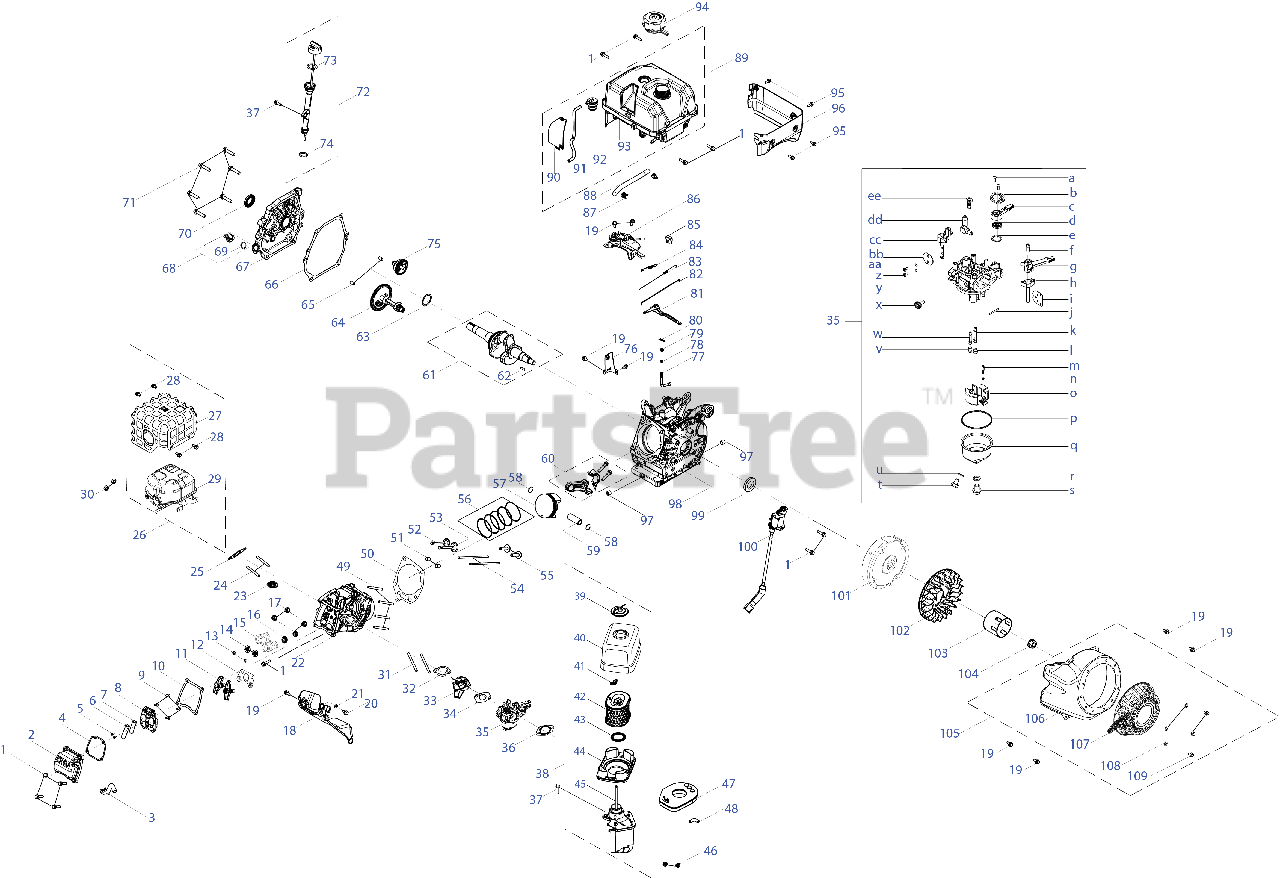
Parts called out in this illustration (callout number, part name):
1	BOLT M6-1 x 25 GR8.8
2	VALVE COVER
3	BREATHER HOSE
4	VALVE COVER GASKET
5	SCREW M3x8
6	BREATHER PLATE
7	BREATHER VALVE
8	INNER VALVE COVER
9	SCREW M5x12
10	VALVE COVER GASKET
11	ROCKER ARM
12	ROCKER ARM BASE
13	VALVE CLIP
14	VALVE SPRING SEAT
15	VALVE SPRING
16	INTAKE VALVE SEAL
17	NUT M8
18	ENGINE SHROUD
19	BOLT M6-1 x 12 GR8.8
20	BOLT M6-1 x 14 GR8.8
21	FLAT WASHER 6x1x18
22	CYLINDER HEAD
23	SPARK PLUG
25	MUFFLER GASKET
26	MUFFLER
27	MUFFLER GUARD
28	BOLT M6x10
29	MUFFLER
31	STUD M6x123
32	INSULATOR GASKET
33	CARBURETOR GASKET
34	CARBURETOR GASKET
35	CARBURETOR
36	INSULATOR
37	BOLT M6-1 x 18 GR8.8
38	AIR FILTER ASSEMBLY
39	PLASTIC WING NUT
40	AIR FILTER COVER
41	WING NUT
42	AIR FILTER ELEMENT
43	AIR FILTER GASKET
44	AIR FILTER BASE (UPPER)
45	AIR FILTER BASE (LOWER)
46	HEX NUT
47	CARBON CANISTER
48	CARBON CANISTER HOSE
49	STUD M8x60
50	CYLINDER HEAD GASKET
51	DOWEL PIN
52	EXHAUST VALVE
53	INTAKE VALVE
54	PUSH ROD
55	TAPPET
56	PISTON RING SET
57	PISTON
58	PISTON PIN SNAP RING
59	PISTON PIN
60	CONNECTING ROD
61	CRANKSHAFT
62	FLYWHEEL KEY
63	THRUST WASHER
64	CAMSHAFT
65	DOWEL PIN
66	CRANKCASE GASKET
67	CRANKCASE COVER
68	OIL PLUG
69	O-RING 15.8 x 2.5
70	OIL SEAL 25 x 41.25 x 6
71	BOLT M8x35
72	DIPSTICK
73	O-RING
74	O-RING
75	GOVERNOR GEAR
76	DIPSTICK BRACKET
77	GOVERNOR GEAR SHFT
78	O-RING
79	GOVERNOR SEAL
80	COTTER PIN
81	GOVERNOR LEVER
82	THROTTLE LINKAGE
83	IDLER SPRING
84	GOVERNOR SPRING
85	THROTTLE KNOB
86	GOVERNOR GEAR BRKT ASM
87	HOSE CLAMP
88	FUEL HOSE
89	Fuel Tank
90	VENT HOSE COVER
91	FUEL HOSE
92	ROLLOVER VALVE
93	FUEL TANK
94	FUEL CAP
95	BOLT: M5 x 14
96	FUEL TANK COVER
97	OIL DRAIN PLUG
98	CRANKCASE
99	OIL SEAL
100	IGNITION MODULE
101	FLYWHEEL
102	COOLING FAN
103	STARTER CUP
104	FLYWHEEL NUT
105	Recoil Starter
106	BLOWER HOUSING
107	RECOIL STARTER
108	RECOIL FLAT WASHER
109	BOLT M6 x 10
